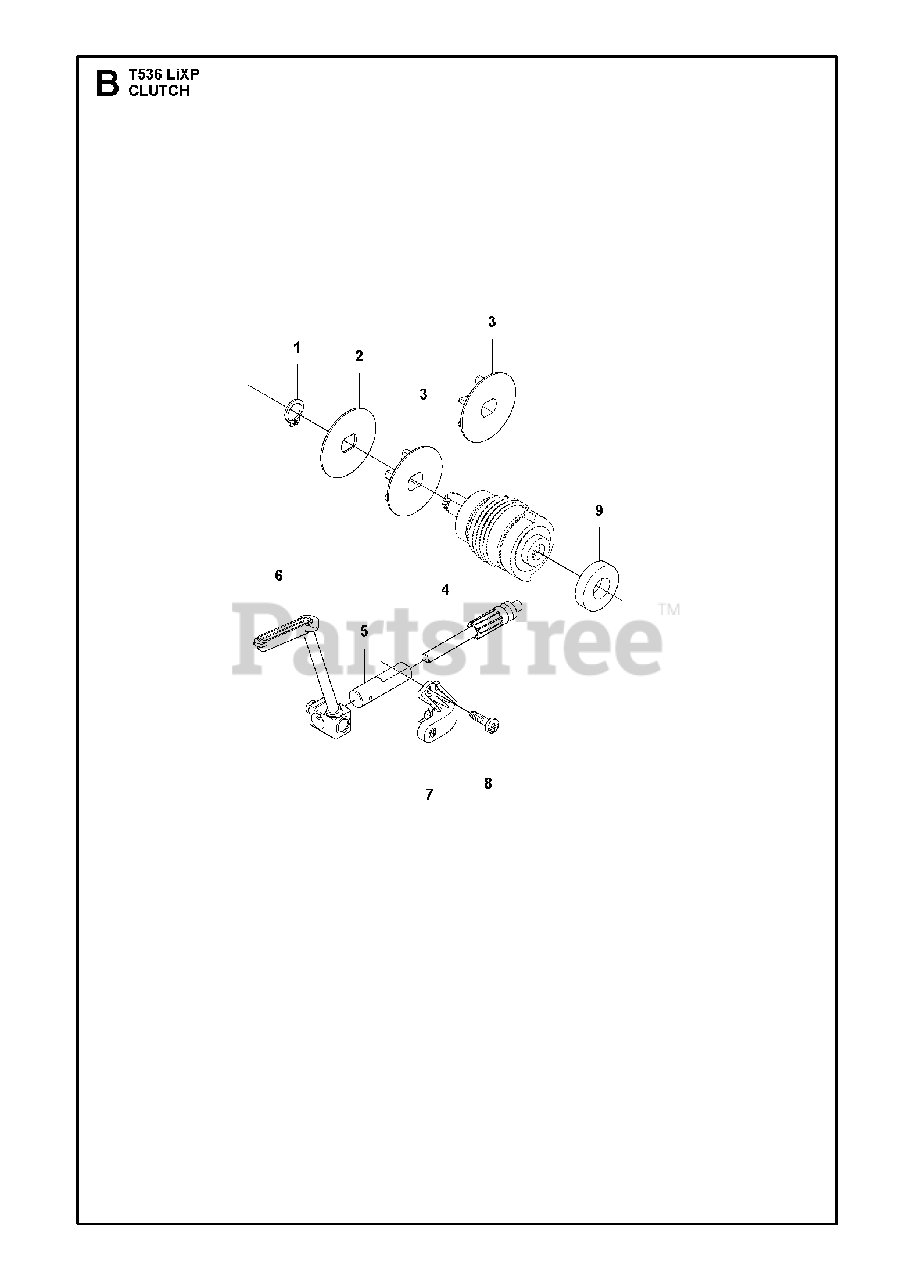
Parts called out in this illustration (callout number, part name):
1	RETAINING RING SGA 10
3	SPUR SPROCKET
3	SPUR SPROCKET 1/4" 8T
4	PISTON PUMP
5	PUMP CYLINDER
